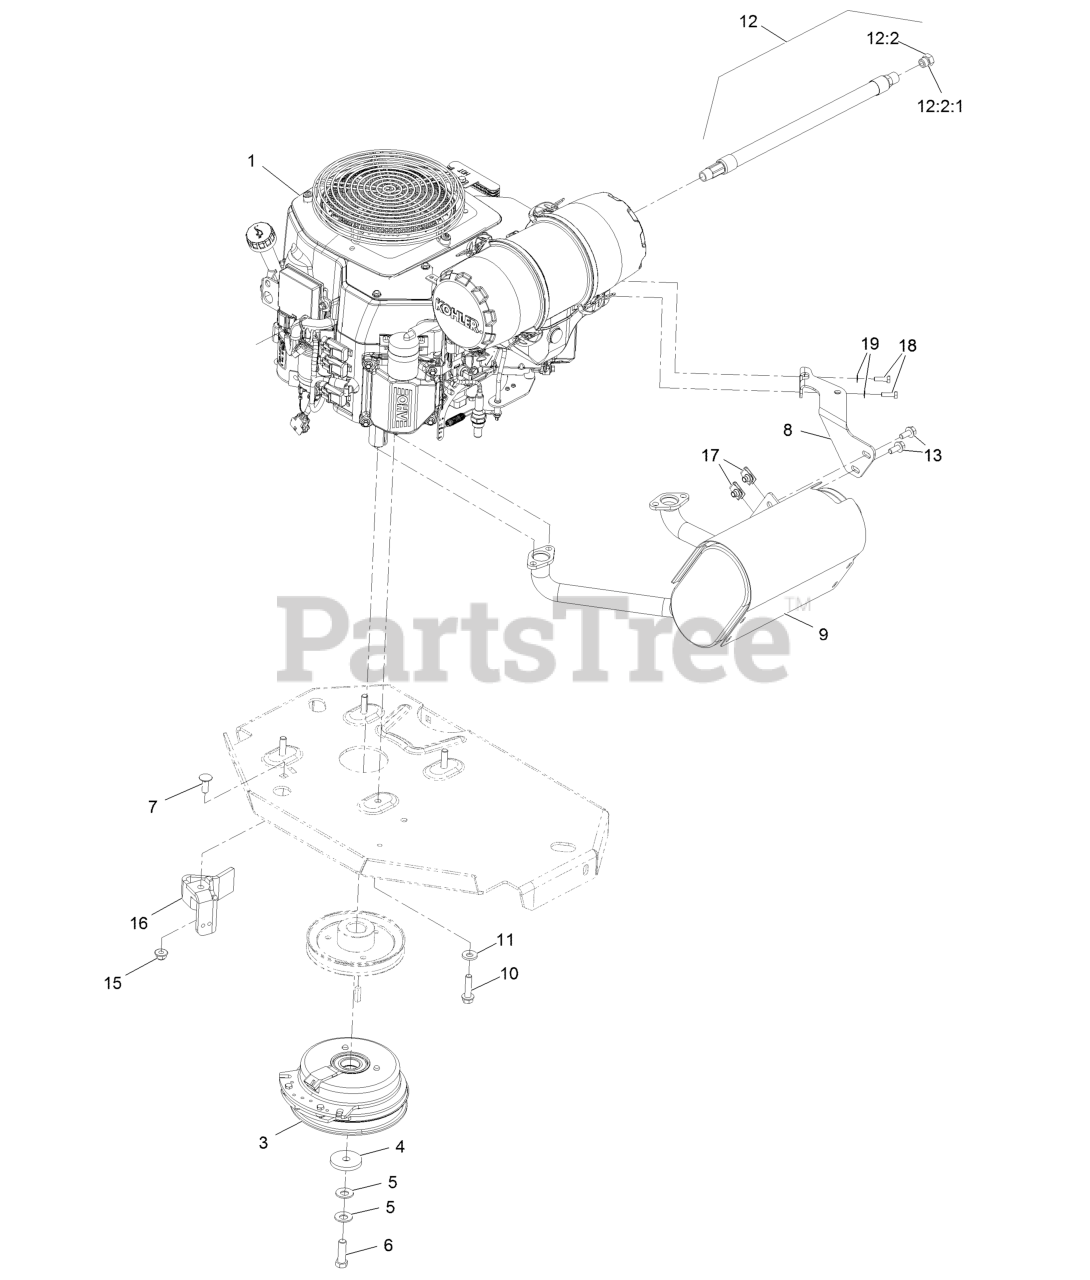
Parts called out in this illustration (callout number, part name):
1	Engine-Kohler, Pcv740 Efi LP
3	CLUTCH KIT
4	WASHER-CLUTCH
5	WASHER-SPRING
6	SCREW-HH 7/16-20 X 1 1/2 W/LOCTITE
7	SCREW-CARR
8	MUFFLER BRACKET KIT
10	SCREW-HWH
11	WASHER-BELLEVILLE
12	OIL DRAIN HOSE ASM
12:2	PLUG-HH
12:2:1	O-RING
13	SCREW-HHF
15	NUT-HF, NI
16	CLUTCH-ANCHOR
18	SCREW-HH M6-1 X 20Mm W/Patch
19	WASHER-SPRING
